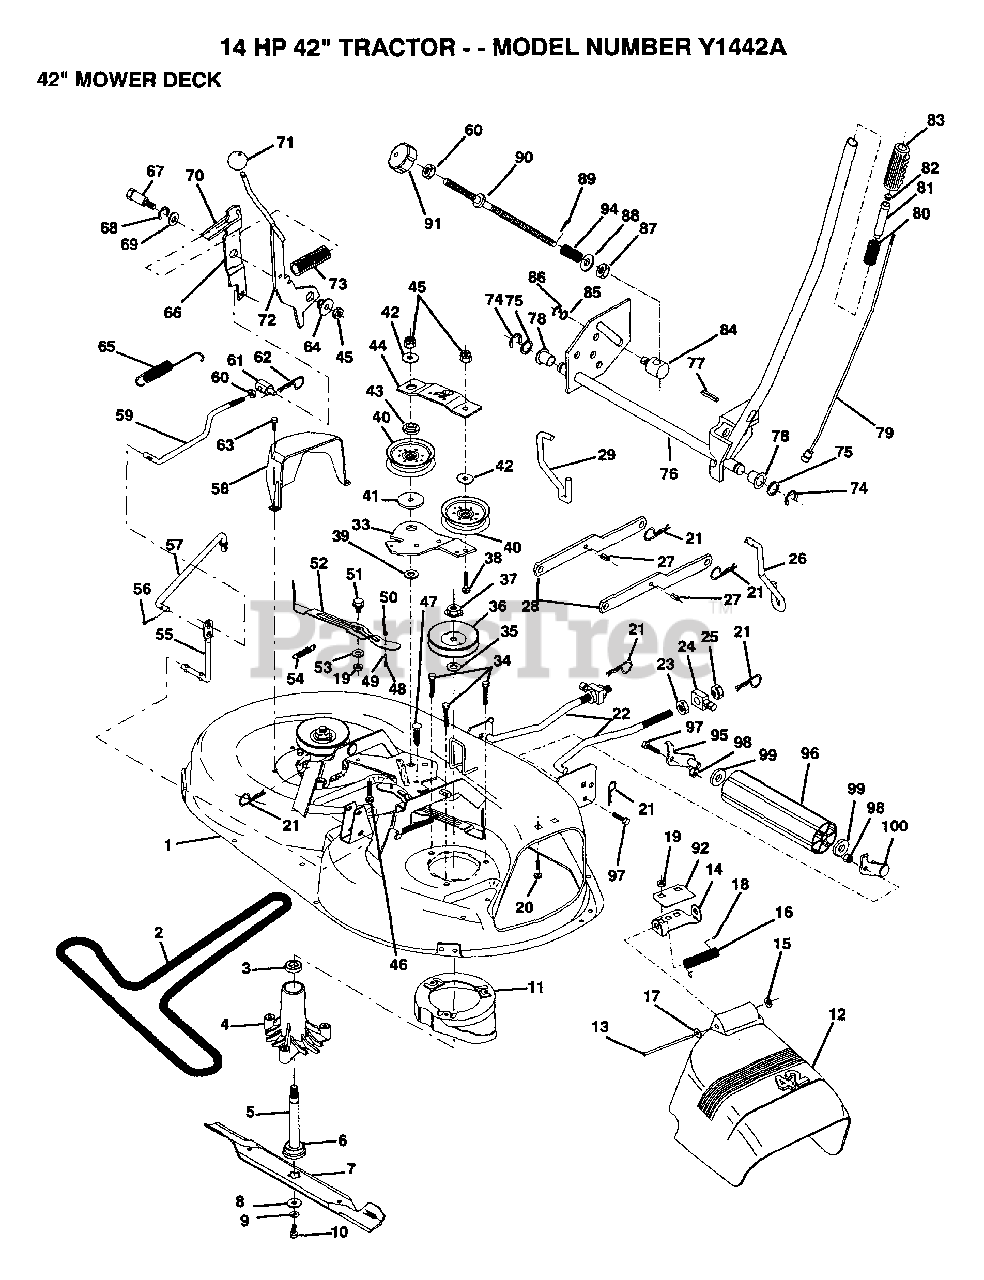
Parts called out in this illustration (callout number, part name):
2	BELT-V.92.4.MWR
3	BEARING
4	HSG ASM MANDREL
6	BEARING.BALL
8	WASHER BLADE
10	BLADE BOLT
12	DEFLECTOR.SHIELD
13	HINGE ROD
14	DEFLECTOR BRKT
15	NUT PUSH M
16	SPRING.(150051)
17	WASHER
18	CAP-SLEEV(107627)
20	BOLT
22	LINK.FRONT
23	NUT
24	TRUNION
25	NUT.LK.W/WSH.1/2.
26	LIFT LINK RH
27	SPRING PIN
29	LINK LIFT LH
33	IDLER ARM
35	WASHER
38	BOLT
39	HARDENED WASHER
40	FLAT IDLER PULLEY
42	WASHER GT
43	RETAINER SPACER
44	IDLER ARM STIFF
46	BOLT CARRIAGE
47	XMAS TREE FASTNER
48	SHOULDER BOLT
50	LOCKNUT
51	Bolt Shoulder 5/16-18 Unc
52	BRAKE PAD ARM ASM
53	HARD SMALL WASHER
54	SPRING EXTENSION
55	PIVOT ROD
57	CLUTCH ROD SECOND
60	NUT
61	TRUNION
62	RETAINER M (5 2)(3 2)
63	SCREW LT
64	BUSHING
65	RETURN SPRING
66	CLUTCH ARM SECOND
67	SHOULDER BOLT
68	RING
69	WASHER
70	SPRING KEEPER
71	KNOB T (1/2-HOLE)
72	CLUTCH ARM PRI AS
75	WASHER
77	PIN-GROOVE LT
78	NYLON BEARING
82	Button Plunger Black
83	GRIP
84	TRUNION LT
85	WASHER
86	KLIP RING
87	NUT T (2 2) (1 2)
88	WASHER
92	STIFFENER BRKT
94	SPRING T
97	BOLT
99	WASHER
